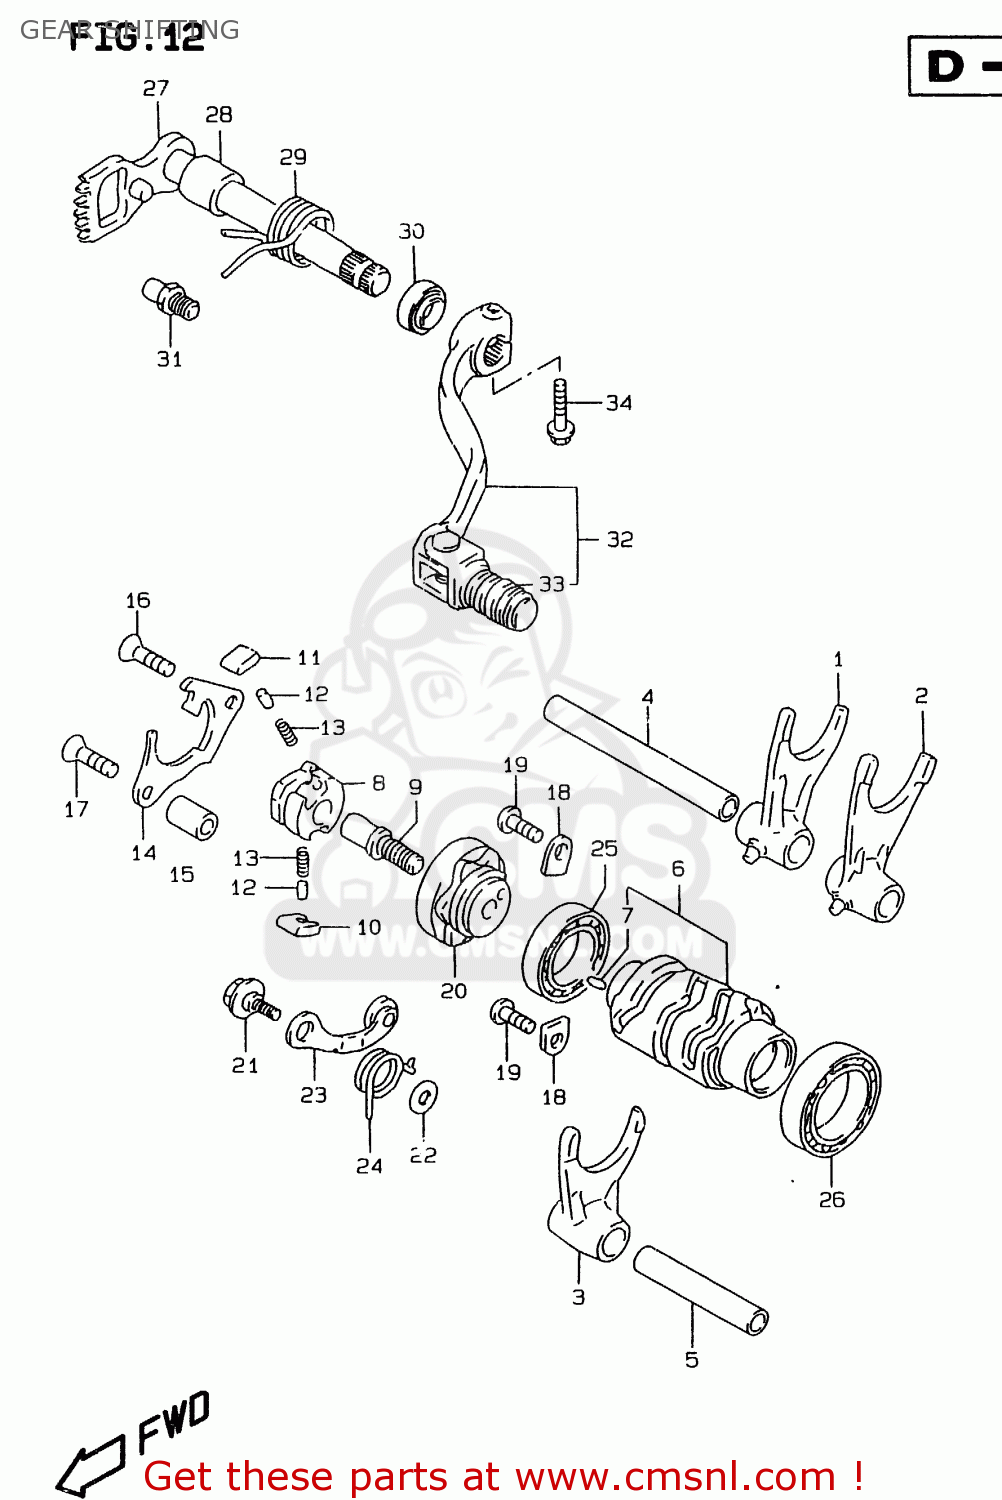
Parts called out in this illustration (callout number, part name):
1	FORK,GEAR SHIFT NO.1
2	FORK,GEAR SHIFT NO.2
3	FORK,GEAR SHIFT NO.3
4	SHAFT,GEAR SHIFT FORK
5	SHAFT,GEAR SHIFT FORK
6	CAM,GEAR SHIFT
7	PIN
8	GEAR,GEARSHIFT CAM DRIVE
9	PIN,SHIFT CAM DRIVEN GEAR
10	PAWL,GEAR SHIFT NO.1
11	PAWL,GEAR SHIFT NO.2
12	PIN(5X8)
13	SPRING
14	LIFTER,GEAR SHIFT POLE
15	SPACER(6.2X12X18)
16	SCREW
17	SCREW
18	RETAINER
19	SCREW
20	PLATE,SHIFT CAM STOPPER
21	BOLT(6X14.3)
22	WASHER
23	STOPPER,SHIFT CAM
24	SPRING
25	BEARING
26	BEARING(30X37X12)
27	SHAFT,GEAR SHIFT
28	SPACER(14X20X17.5)
29	SPRING
30	SEAL,OIL(14X22X6)
31	STOPPER,GEAR SHIFT CAM
32	LEVER ASSEMBLY,GEAR SHIFTING
33	RUBBER,GEAR SHIFT PEDAL
34	SCREW
